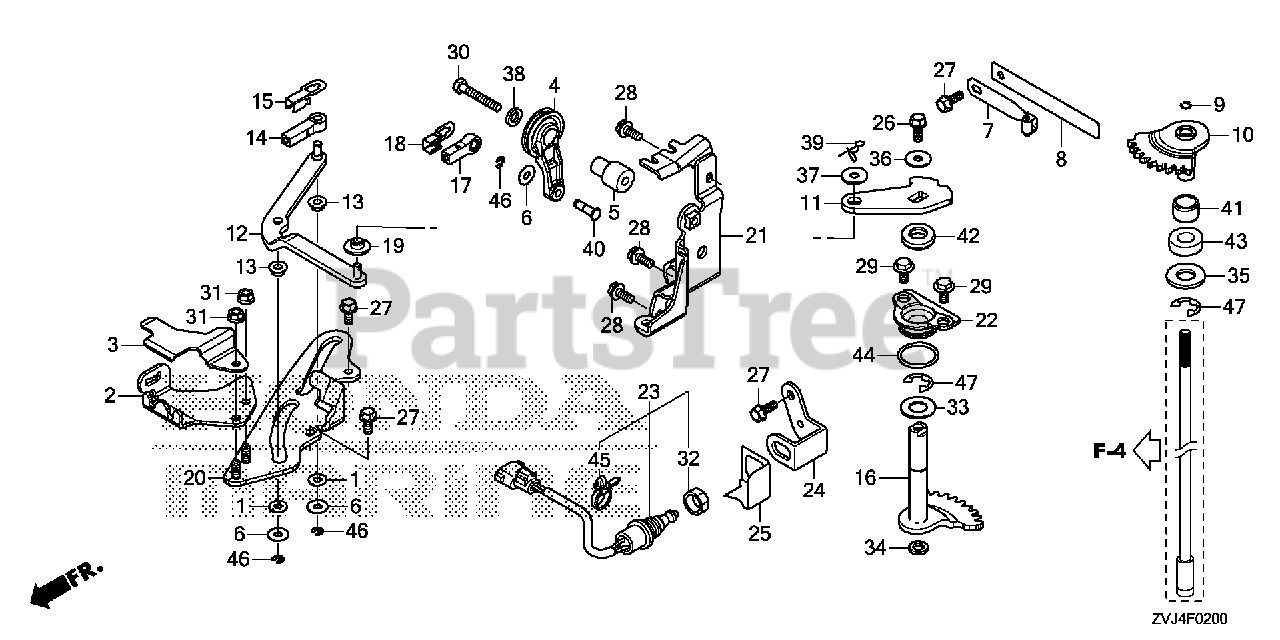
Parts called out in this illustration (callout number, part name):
1	WASHER, AIR CLEANER COVER SETTING
2	PLATE, REMOTE CONTROL CABLE
3	COVER, REMOTE CONTROL CABLE
4	ARM, THROTTLE
5	SHAFT, THROTTLE ARM
6	WASHER, PIVOT
7	SPRING, CLICK
8	SPRING, CLICK ASSIST
9	RING, STOPPER
10	SHAFT, SHIFT (A)
11	ARM, SHIFT (MECH)
12	ROD, LINK (MECH)
13	COLLAR, SHIFT SLIDER
14	PIVOT, SHIFT
15	PLATE, LOCK
16	SHAFT, SHIFT (B)
17	PIVOT, THROTTLE
18	PLATE, LOCK
19	BUSH, SHIFT ARM
20	GUIDE, SHIFT LINK (MECH)
21	BRACKET, SHIFT LINK (MECH)
22	HOLDER, SEAL
23	SWITCH ASSY., NEUTRAL
24	BRACKET, NEUTRAL SWITCH
25	COVER, NEUTRAL SWITCH
26	BOLT, FLANGE (6X16)
27	BOLT, FLANGE (6X14)
28	BOLT-WASHER (6X16)
29	BOLT, FLANGE (6X11)
30	BOLT, HEX. (6X40)
31	NUT, FLANGE (6MM)
32	NUT, HEX. (20MM)
33	WASHER, THRUST (14MM)
34	WASHER B, THRUST (14MM)
36	WASHER, PLAIN (6MM)
37	WASHER, PLAIN (6MM)
38	WASHER, PLAIN (6MM)
39	PIN, SNAP (6MM)
41	RING (INNER) (15X20X13)
42	OIL SEAL (14X26X6)
43	SEAL, WATER (14X26X8)
44	O-RING (26.9X2.4) (NOK)
45	CLIP, HARNESS BAND (145MM) (BLACK)
46	E-RING (4MM)
47	E-RING (12MM)
